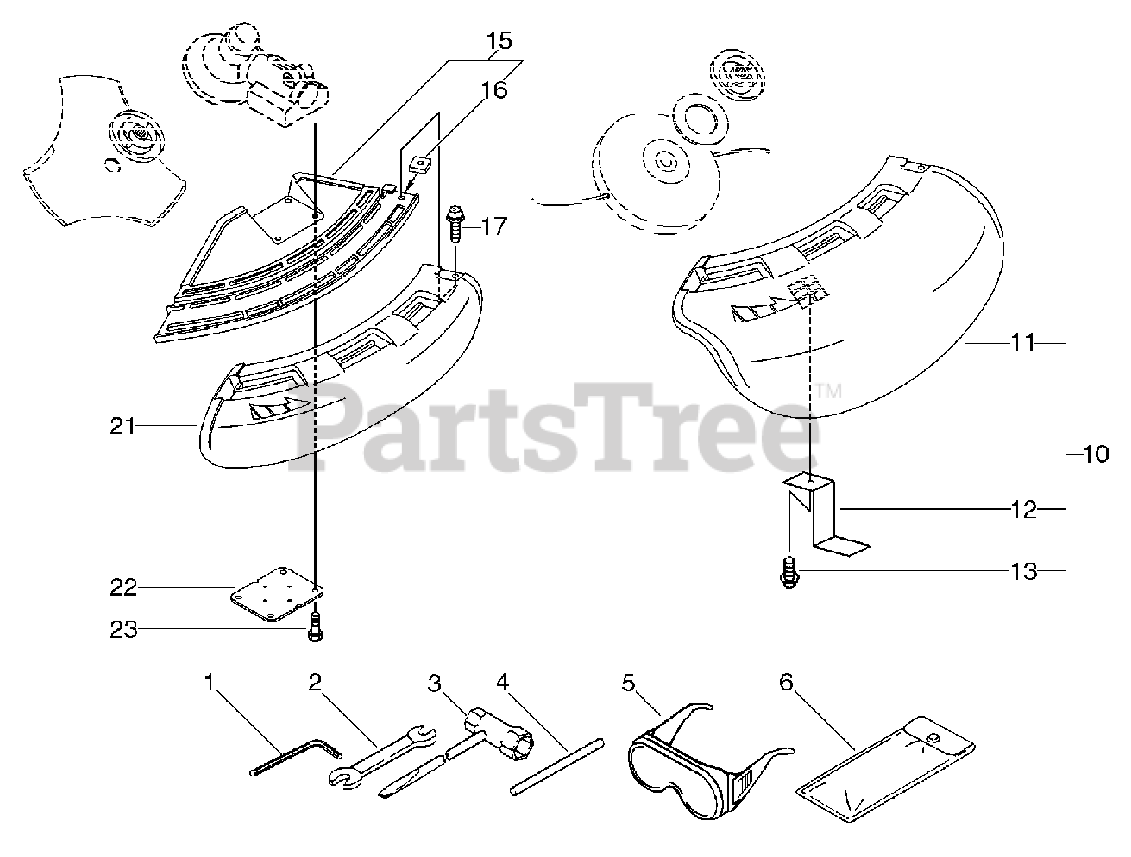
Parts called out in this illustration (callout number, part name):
1	WRENCH, ALLEN 4 MM
2	SPANNER 8×10
3	T-WRENCH
3	T-WRENCH 17x-19 L200
4	TOOL, LOCKING 5×120 MM
5	GOGGLES
5	GLASSES, SAFETY
6	BAG, TOOL
10	DEBRIS SHIELD ASSY
11	SHIELD, DEBRIS
12	CUTTER, LINE
13	SCREW, TAPPING 5×12
16	NUT M5
17	SCREW 5×18
20	BRACKET ASSY, SHIELD
21	SHIELD, BLADE
22	PLATE, SHIELD
23	BOLT 5×25
